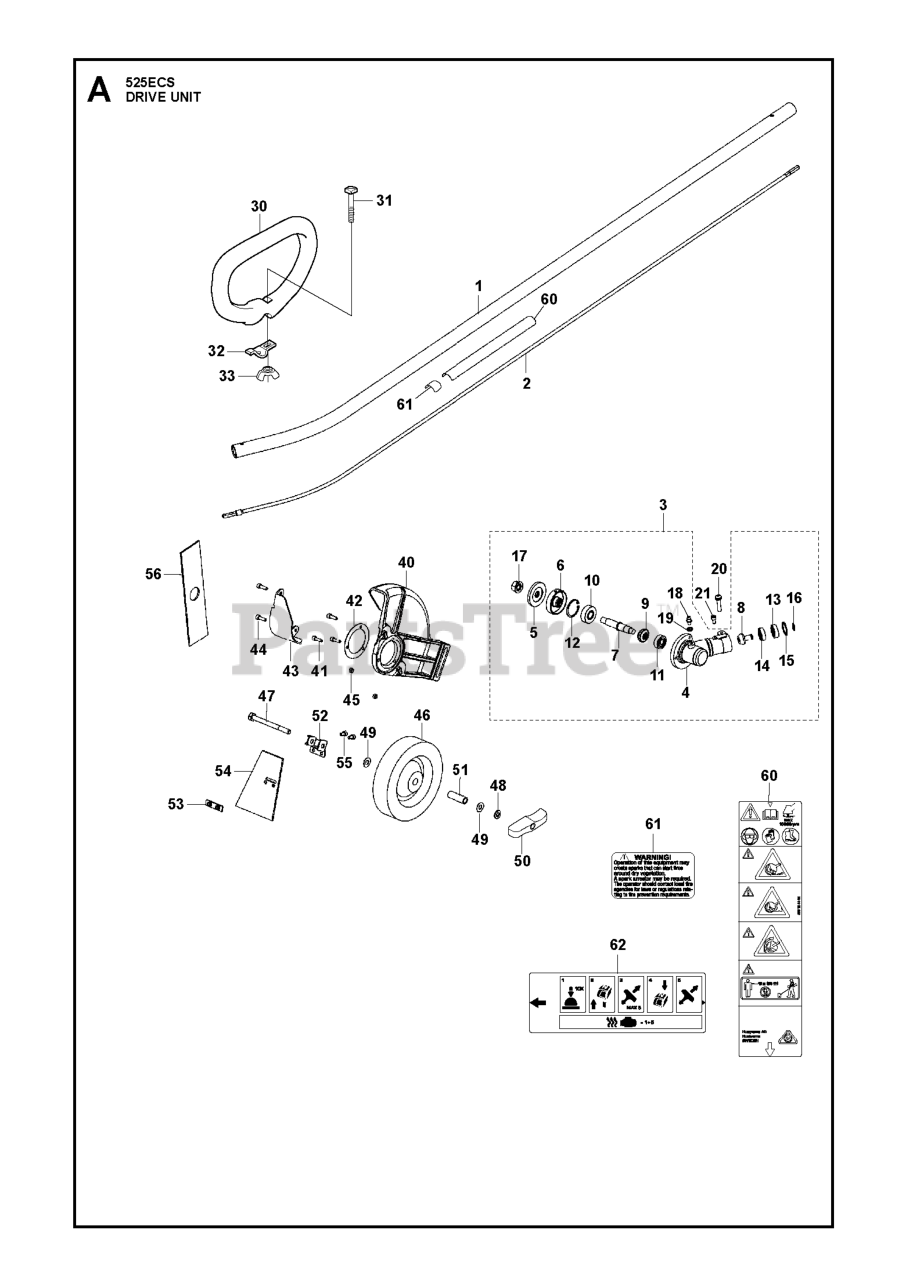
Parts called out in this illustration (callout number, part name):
2	FLEX SHAFT
3	GEARCASE ASSY
7	SHAFT GEAR
10	BEARING***
15	RP_RING
30	HANDLE, LOOP
32	HOLDER
43	Protection
56	BLADE 7.52X2X.125
61	DECAL SPARK ARRESTOR WARNING
62	DECAL START REMINDER 523/525
